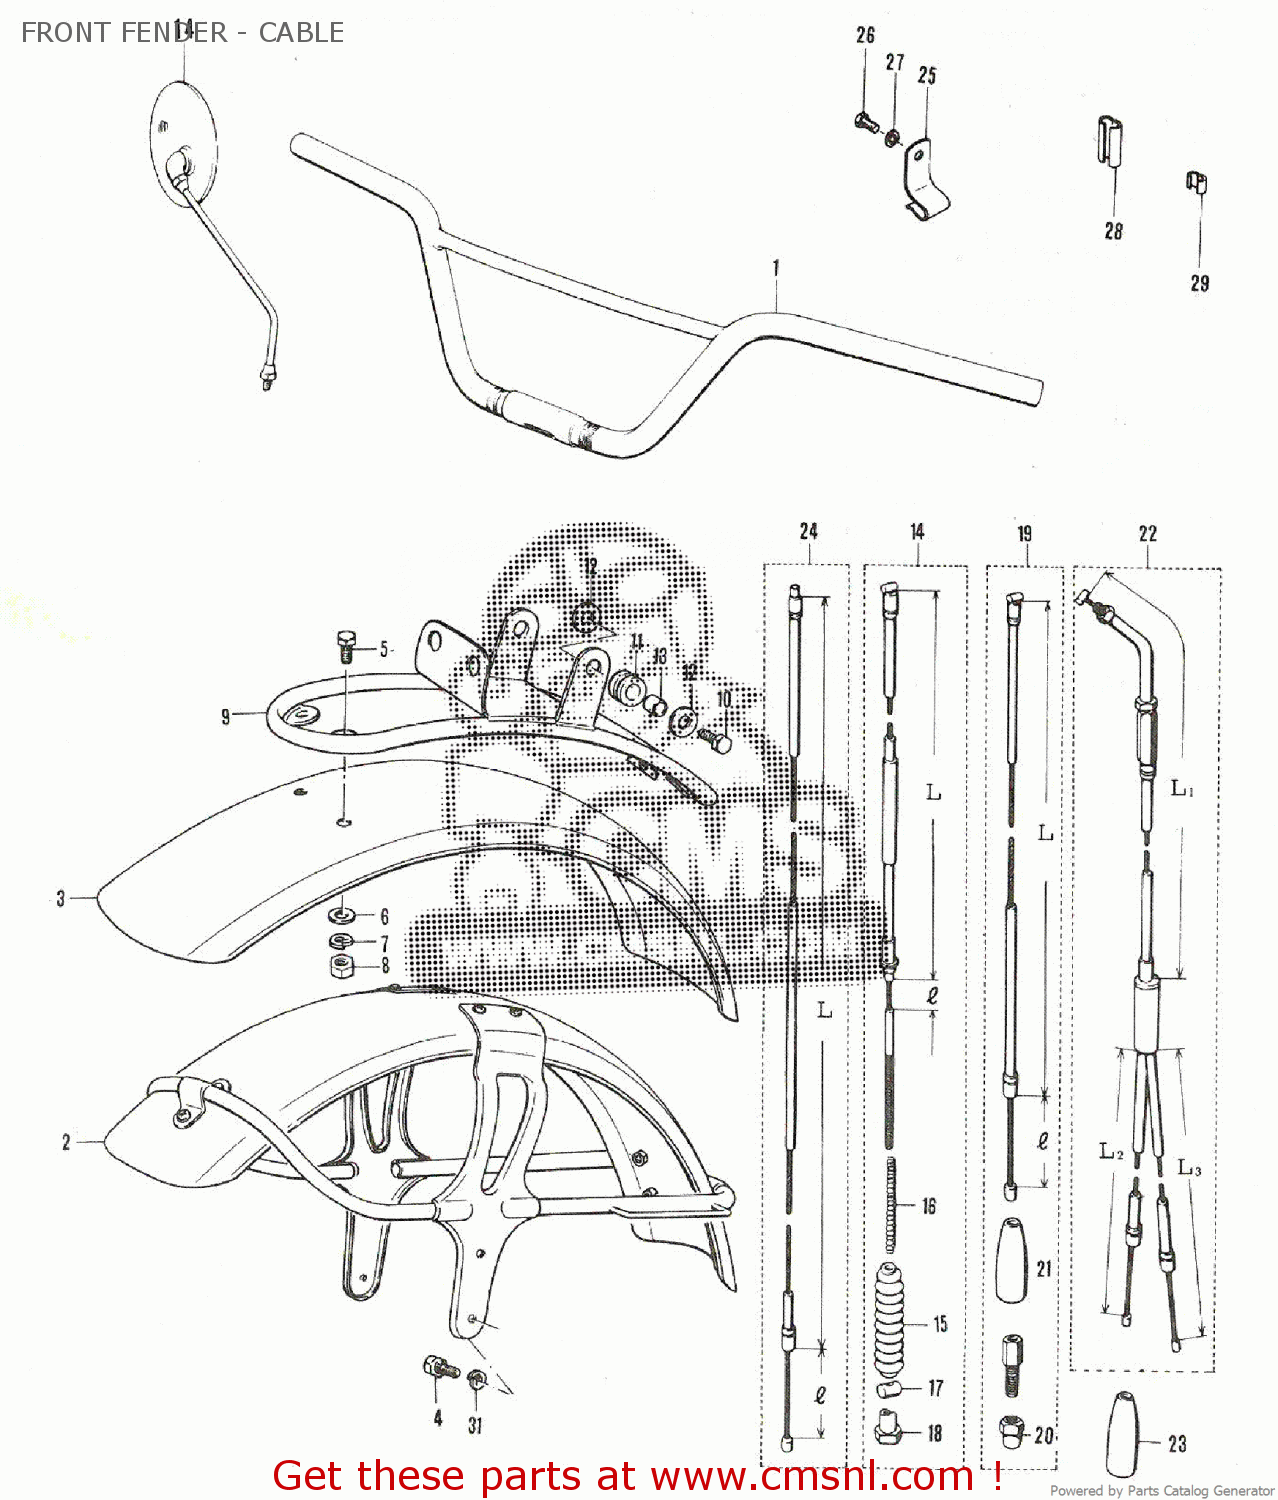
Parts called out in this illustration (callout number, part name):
1	HANDLEBAR
2	FENDER,FRONT
4	SMALL HEAD HEXAGON BOLT
14	CABLE ASSEMBLY,FRONT BRAKE
15	SEAL,DUST(7X16X75)
16	SPRING
17	PIN,10X19
18	NUT
19	CABLE ASSY,CLUTCH
20	NUT
21	DUST SEAL
22	CABLE ASSEMBLY,THROTTLE
23	DUST SEAL
24	CABLE,STARTER
25	CLAMP
26	HEXAGON BOLT
27	LOCK WASHER
28	CLIP
29	CLIP
31	LOCK WASHER
